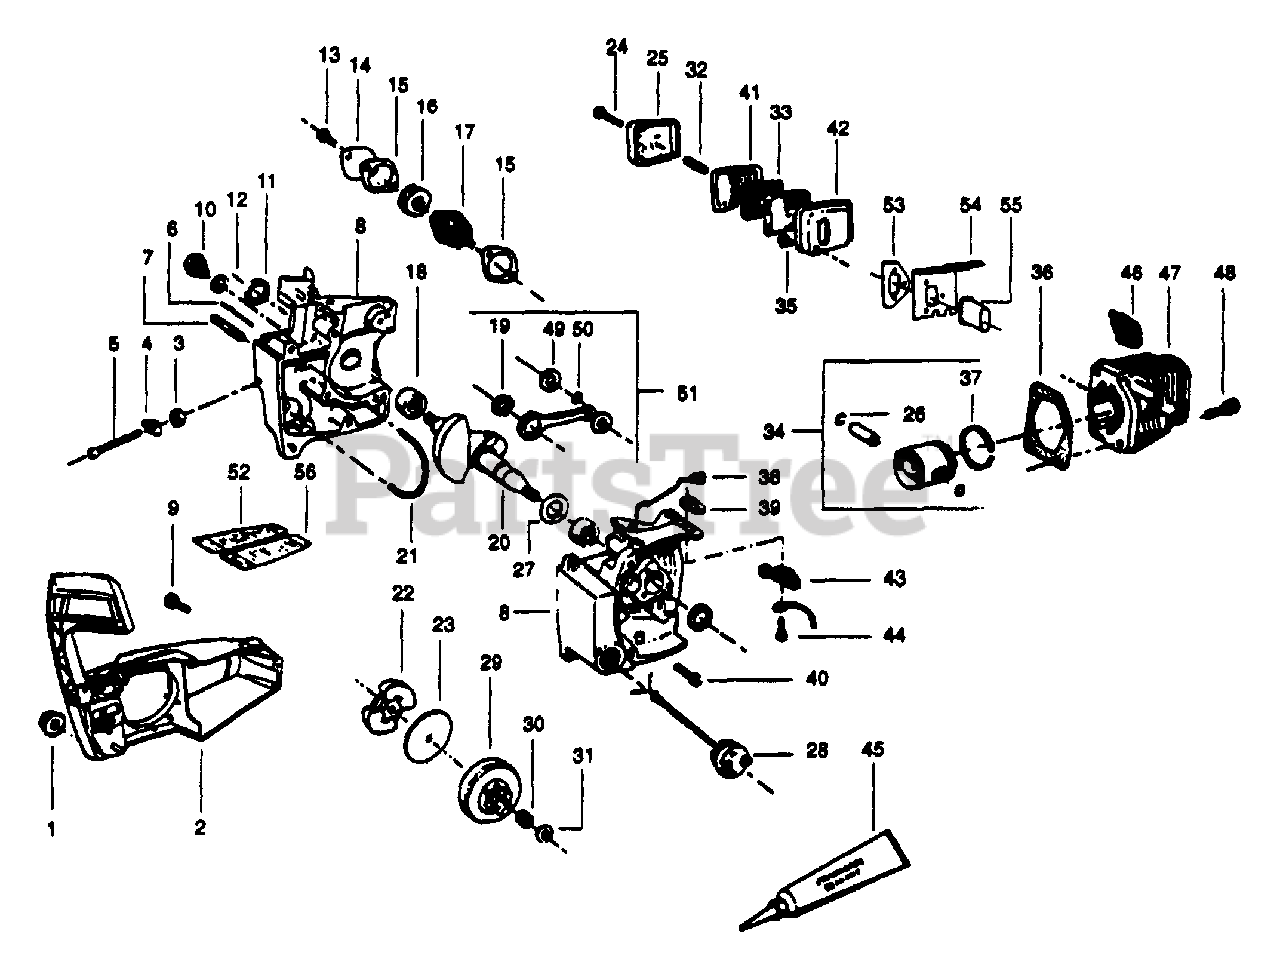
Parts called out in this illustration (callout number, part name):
1	Bar Mounting Nut
2	Chain Brake Kit
4	Bar Adjust Pin
6	Oil Tank Vent Pin
7	Bar Mounting Stud
8	Crankcase Ass'y
10	Check Valve Kit
11	Crankshaft Seal
12	Check Valve Gasket
14	Metering Body Cover
15	Metering Body Gasket
16	Oil Filter
17	Metering Body Ass'y.
18	Crankshaft Bearing
19	Roller Bearings
20	Crankshaft
21	Oil Discharge Line
22	Clutch Ass'y. Kit
23	Clutch Washer Kit
25	Muffler Cover
26	Piston Pin Retainer
27	Thrust Washer
28	Oil Cap Ass'y.
29	Clutch Drum
30	Clutch Bearing
31	Clutch Spacer
33	Spark Arrestor Screen
34	Piston Kit
36	Cylinder Gasket
37	Piston Ring
38	Switch Knob Ass'y
39	Ramp Switch
41	Muffler Baffle
42	Muffler Body
43	Switch Clamp
45	Crankcase Sealant
46	Spark Plug
50	Bearing Rod
51	Connection Rod Ass'y. Kit
52	Instruction Decal Right Hand
53	Gasket-Muffler
54	Muffler-Back Plate
55	Port-Insulator
56	Instruction Decal Left Hand
